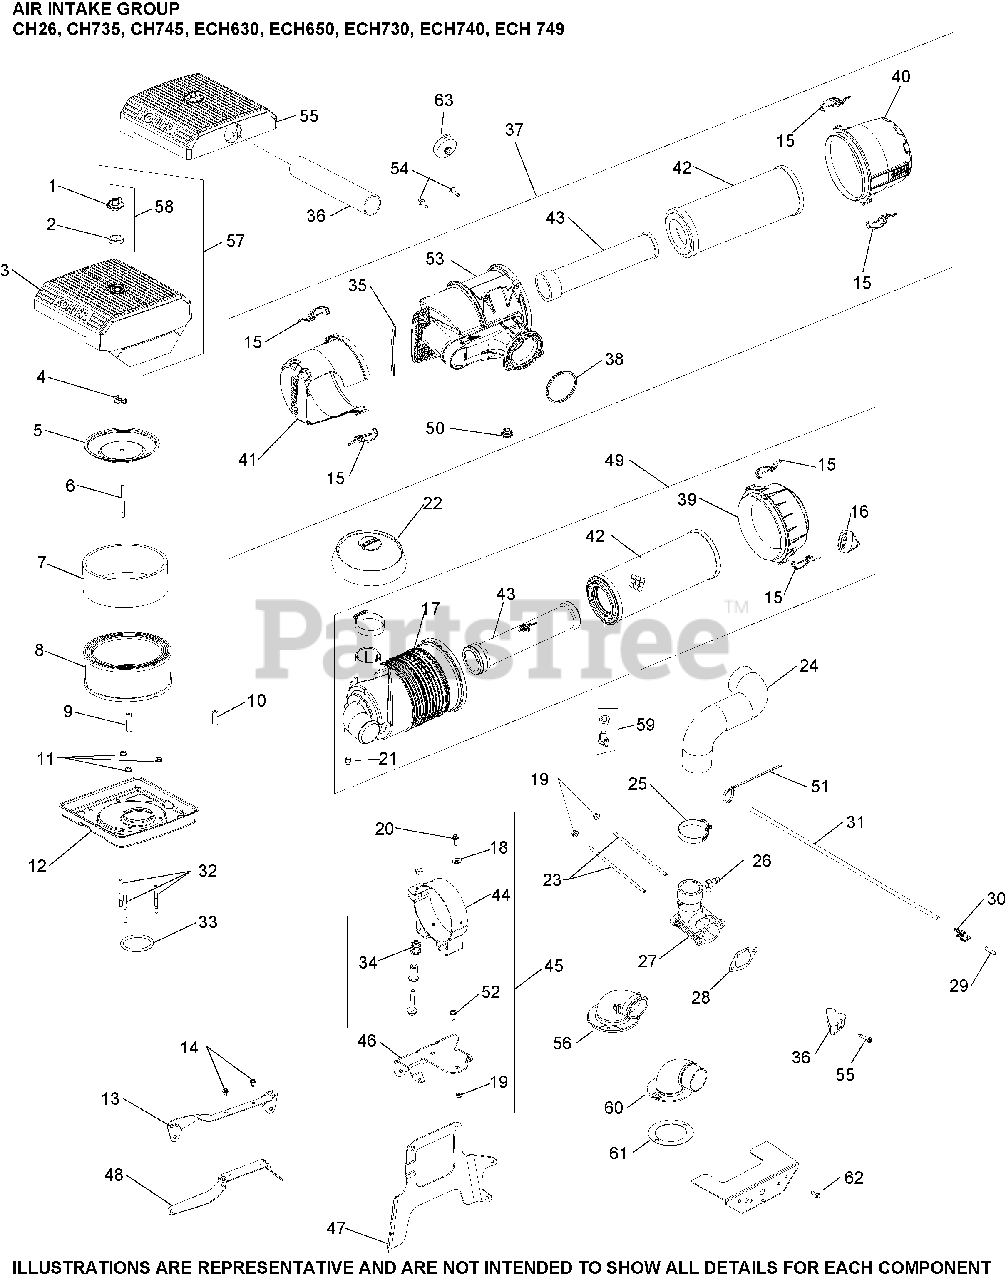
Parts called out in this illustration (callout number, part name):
1	KNOB, COVER
3	COVER, AIR CLEANER
4	NUT, WING
5	COVER, INNER AIR CLEANER
7	ELEMENT, PRECLEANER (LOW)
8	ELEMENT, AIR CLEANER - Also available Retail Packaged 47 883 03-S1 Air Filter Kit
11	NUT, FLG M6X1.0
12	BASE, AIR CLEANER
13	BRACKET, AIR CLEANER BASE
14	SCREW, THREAD FORMING
29	CAP, MASKING
30	CONNECTOR, EVAPORATIVE
32	STUD, LOW PROFILE A/C
33	O-RING, AIR CLEANER BASE
57	KIT, AIR CLEANER COVER
58	KIT, KNOB W/SEAL
62	SCREW, HI-LOW
